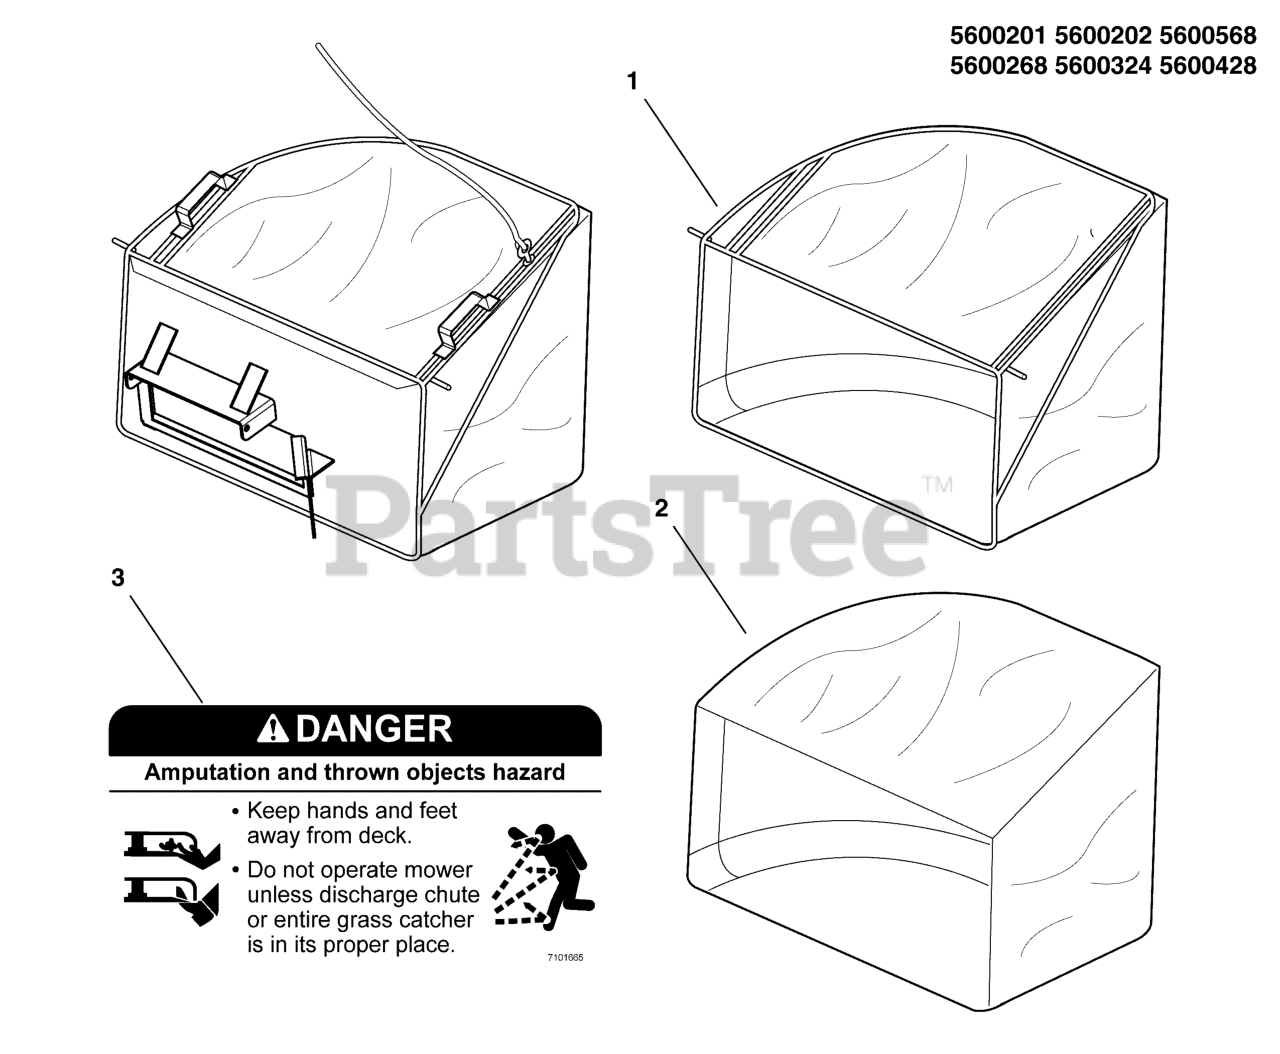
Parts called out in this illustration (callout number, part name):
1	COLLECTION BAG, SW-20, 3.25 BUSHEL - NET
2	3.25 BUSHEL BAG - 305-001-113
3	DECAL, DANGER DO NOT OPERATE W/O DEFLECT
